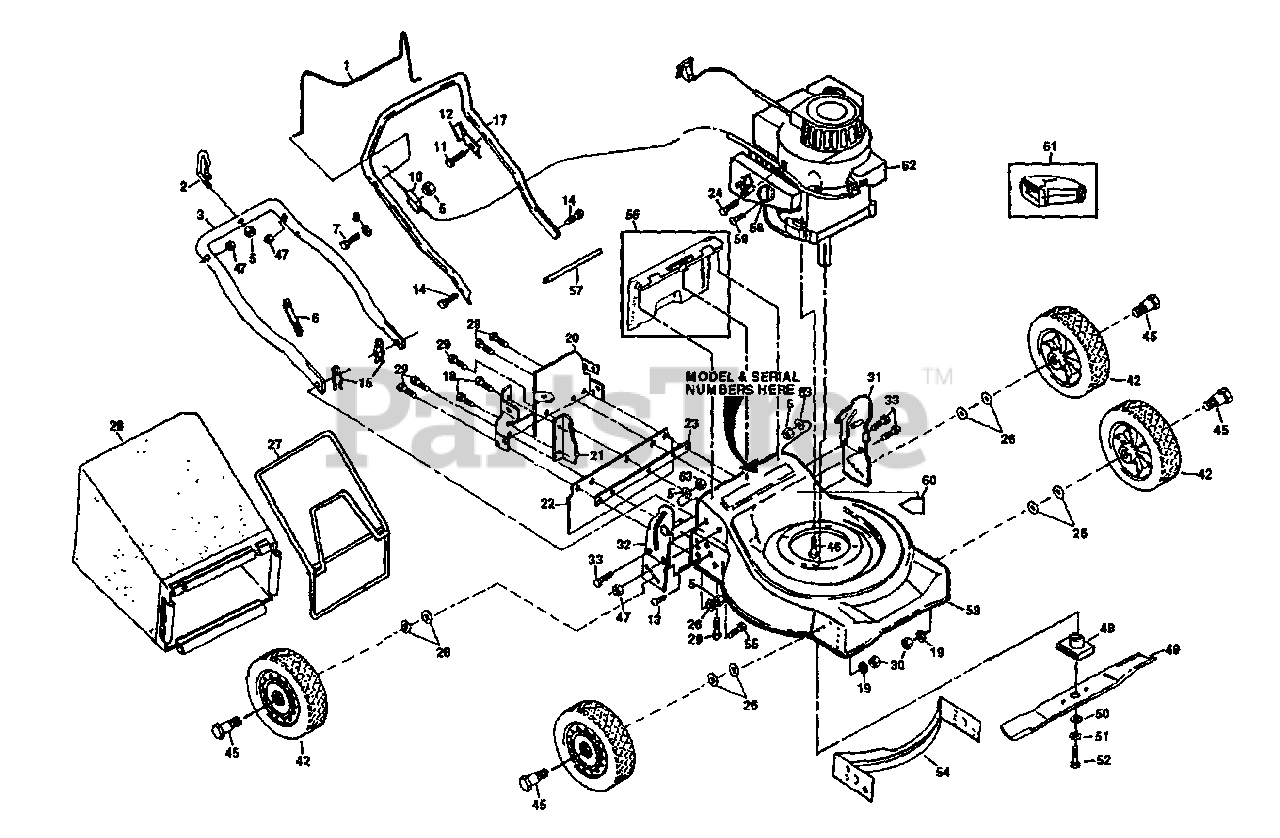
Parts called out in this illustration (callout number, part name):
1	Control Bar
2	Rope Guide
3	Lower Handle
6	Wire Tie
10	Engine Zone Control Cable
12	Up-Stop Bracket
15	Hairpin Cotter
17	Upper Handle
20	Back Plate
21	Side Baffle
22	Rear Skirt
23	Backing Strip
27	Catcher Frame
28	Grass Bag
29	Hex Tapping Screw
31	Handle Bracket Assembly (Left)
32	Handle Bracket Assembly (Right)
42	Wheel & Tire Assembly 7.00 x 3.5
45	Bolt, Shoulder 3/8- 16 x 2.5
48	Blade Adapter
49	20 Blade
50	Hardened Washer
52	Hex Head Screw 3/8-24 x 1-3/8
53	Lawn Mower Housing Kit
54	Front Baffle
56	Rear Door Kit
58	Muffler Deflector
59	Screw
60	Danger Decal
61	MA35 Clipping Deflector
63	Washer
